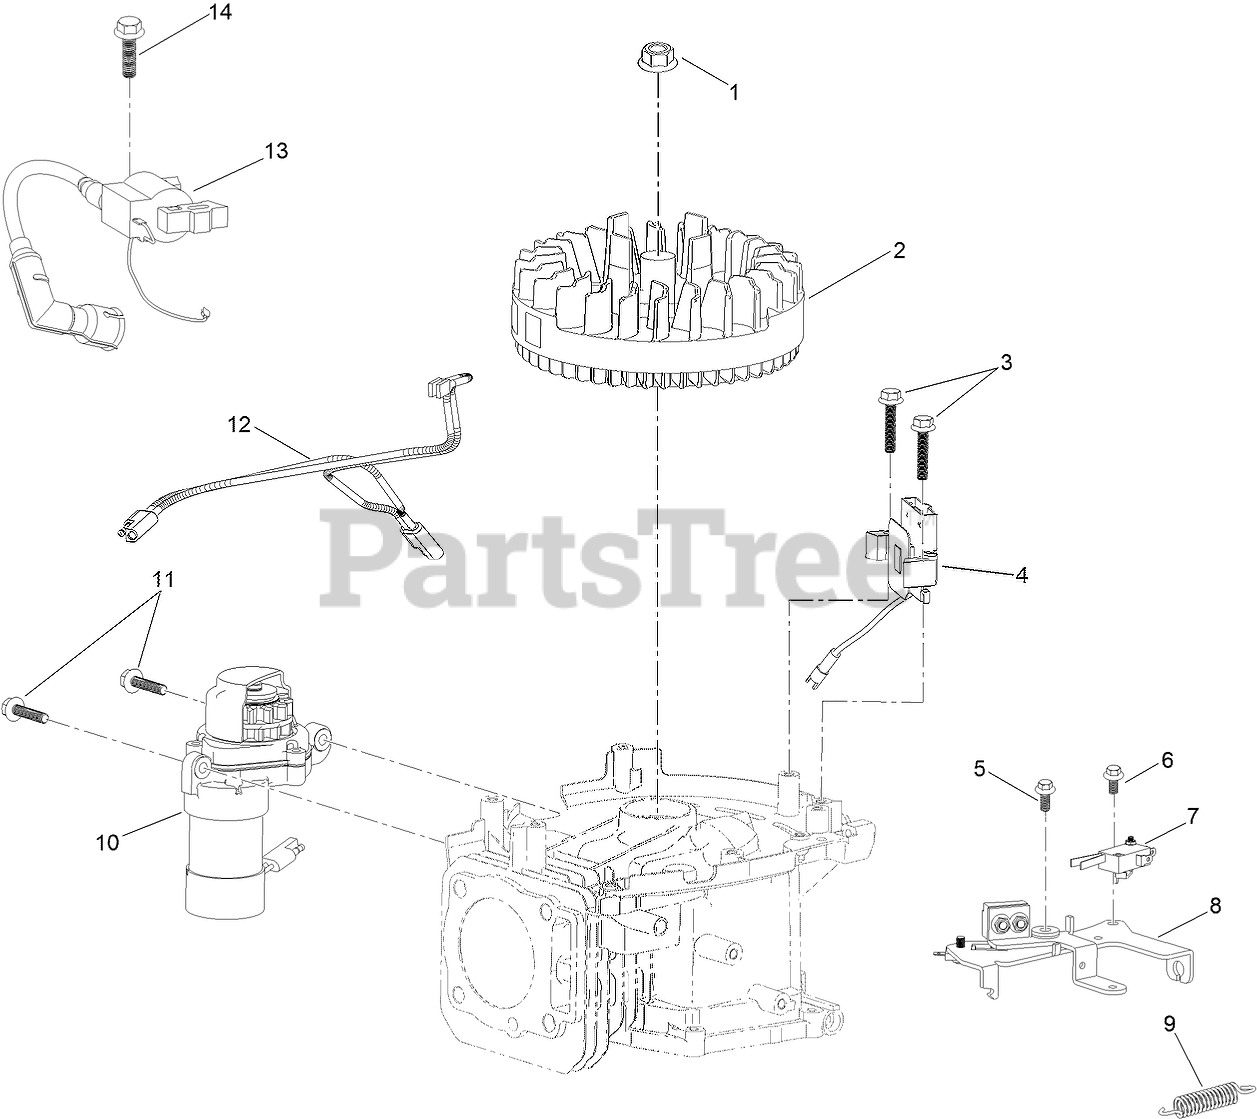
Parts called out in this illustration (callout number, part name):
1	NUT-FLANGE
2	FLYWHEEL
3	SCREW-HHF
4	ALTERNATOR
5	BOLT-FLANGE
6	SCREW-HHF
7	SWITCH-STOP, ENGINE
8	BRAKE ASM
9	SPRING-BRAKE
10	MOTOR-STARTER
11	SCREW-HHF
12	HARNESS-MOTOR, STARTER
13	IGNITION COIL ASM
14	SCREW-HHF
